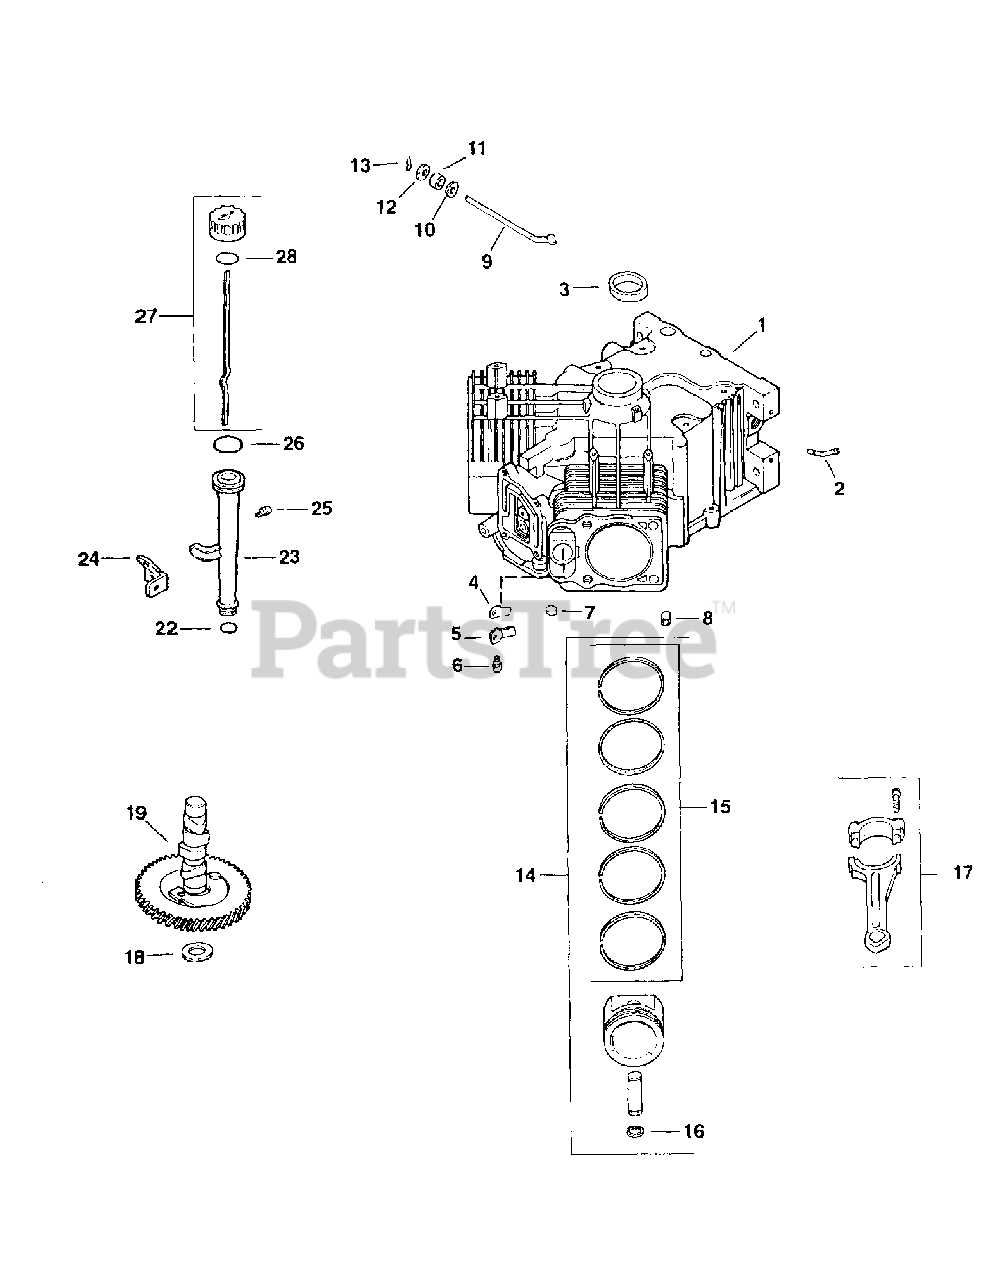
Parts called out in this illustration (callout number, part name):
1	Crankcase
3	Seal, Oil
4	Reed, Breather
5	Retainer, Reed
6	Screw, Hex Flange
7	Plug, Cup
8	Pin, Dowel Locating
9	Shaft, Governor Cross
10	Washer, Plain 1/4"
11	Seal, Governor Cross Shaft
12	Washer, Plain 1/4"
13	Pin, Hitch
14	Piston w/Ring Set (Std.)
14	Piston w/Ring Set (.25)
14	Piston w/Ring Set (.50)
15	Ring Set (Std.)
15	Ring Set (.25)
15	Ring Set (.50)
16	Retainer, Piston Pin
17	Connecting Rod (Std.)
18	Shim, Camshaft (A.R.) (White) .02725-.02875
18	Shim, Camshaft (A.R.) (Blue) .02925-.03075
18	Shim, Camshaft (A.R.) (Red) .03125-.03275
18	Shim, Camshaft (A.R.) (Yellow) .03325-.03475
18	Shim, Camshaft (A.R.) (Green) .03525-.03675
18	Shim, Camshaft (A.R.) (Gray) .03725-.03875
18	Shim, Camshaft (A.R.) (Black) .03925-.04075
19	Camshaft
23	Tube, Oil Fill
24	Bracket, Oil Fill Tube
25	Screw, Hex Flange
27	Dipstick Assembly
